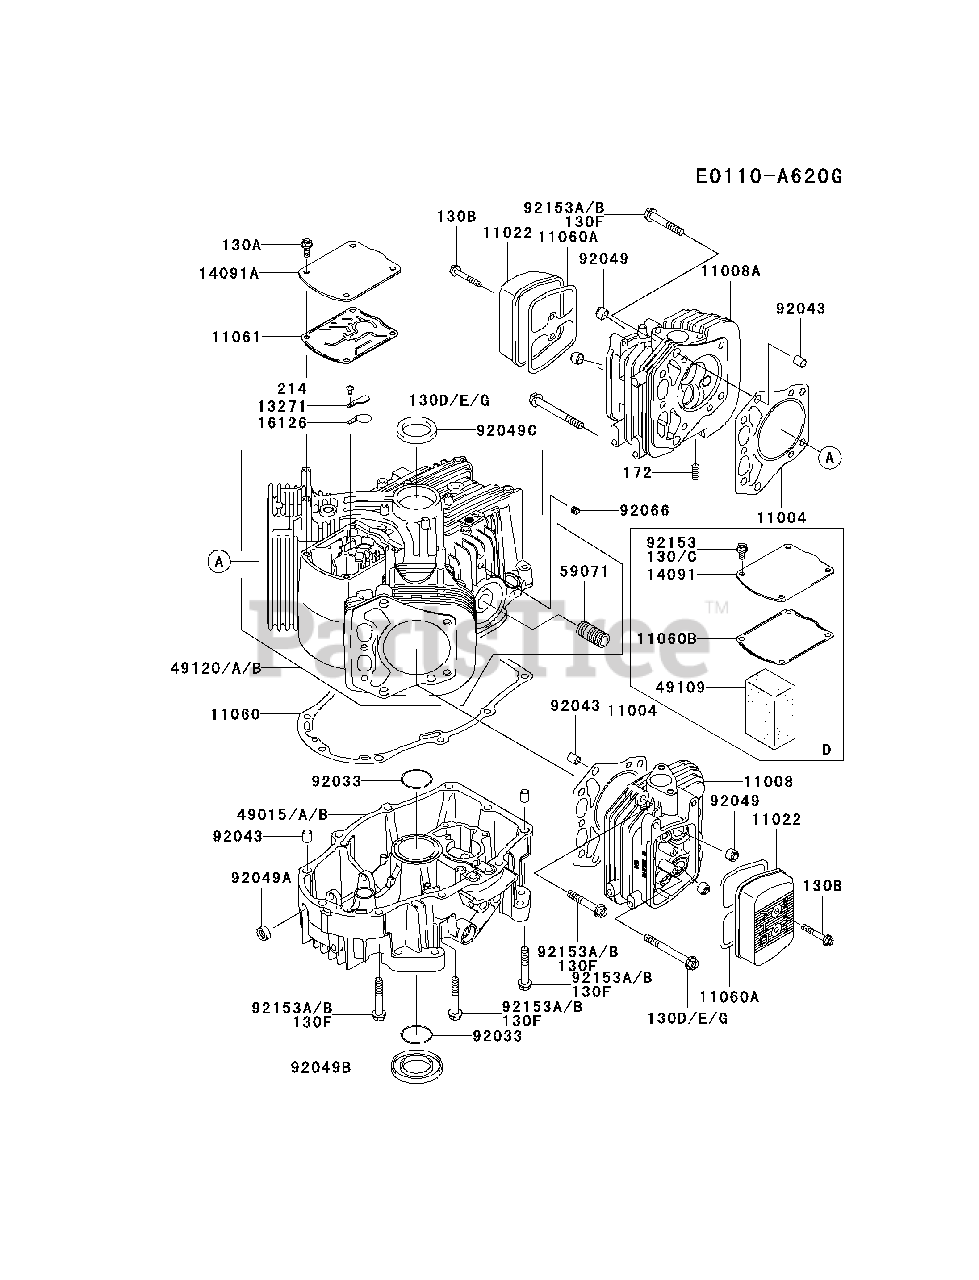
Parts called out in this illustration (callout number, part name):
130	BOLT-FLANGED,6X12
130A	BOLT-FLANGED,6X16
130B	BOLT-FLANGED,6X40
130C	BOLT-FLANGED,6X12
130E	BOLT-FLANGED,8X75
130F	BOLT-FLANGED,8X50
130G	BOLT-FLANGED,8X75
172	BOLT-STUD,8X18
214	SCREW-PAN+-,4X8
